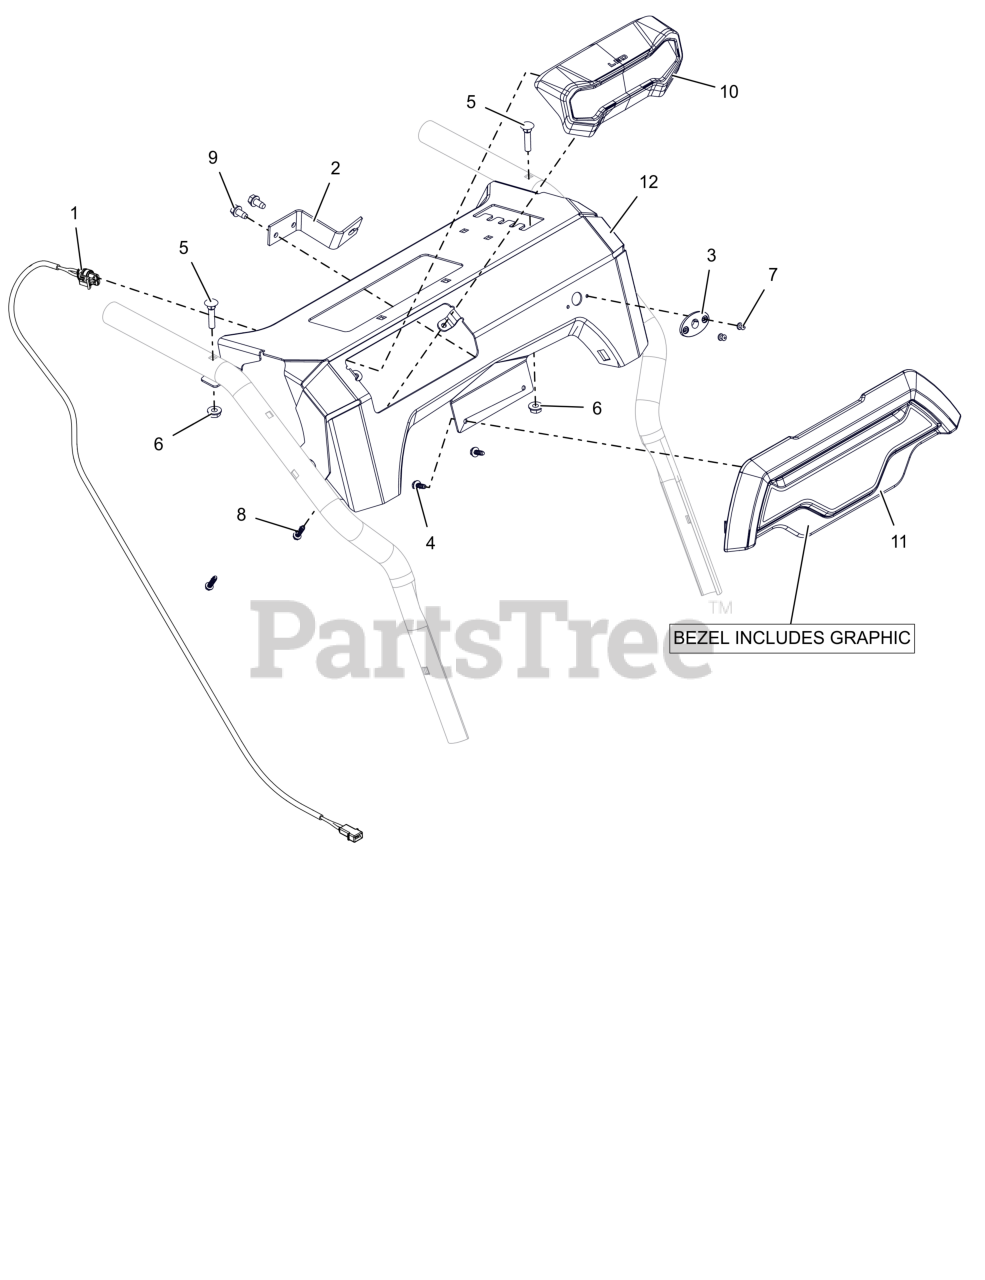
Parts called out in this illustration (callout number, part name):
1	HARNESS- WIRE - LT
2	ANCHOR, DEFLECTOR CABLE
3	BSHG, CHUTE CRANK
4	SCR, PLASTIC #10X.50
5	BLT-RDHDXLSQNK.25-20X1.25 G5ZC
6	NUT-LK-CTR-FLG .25-20 ZC120
7	RVT-POP #43 .125X.313 STL ZINC
8	SCR-HWH 10-16X.75 HI-LO ZCC
9	SCR-TAP .25-20X.50 HWH ZCC
10	HEADLIGHT ASM- LED
11	BEZEL- SMALL - DELUXE
12	PANEL, DASH - SM DASH DLX W/DECAL
